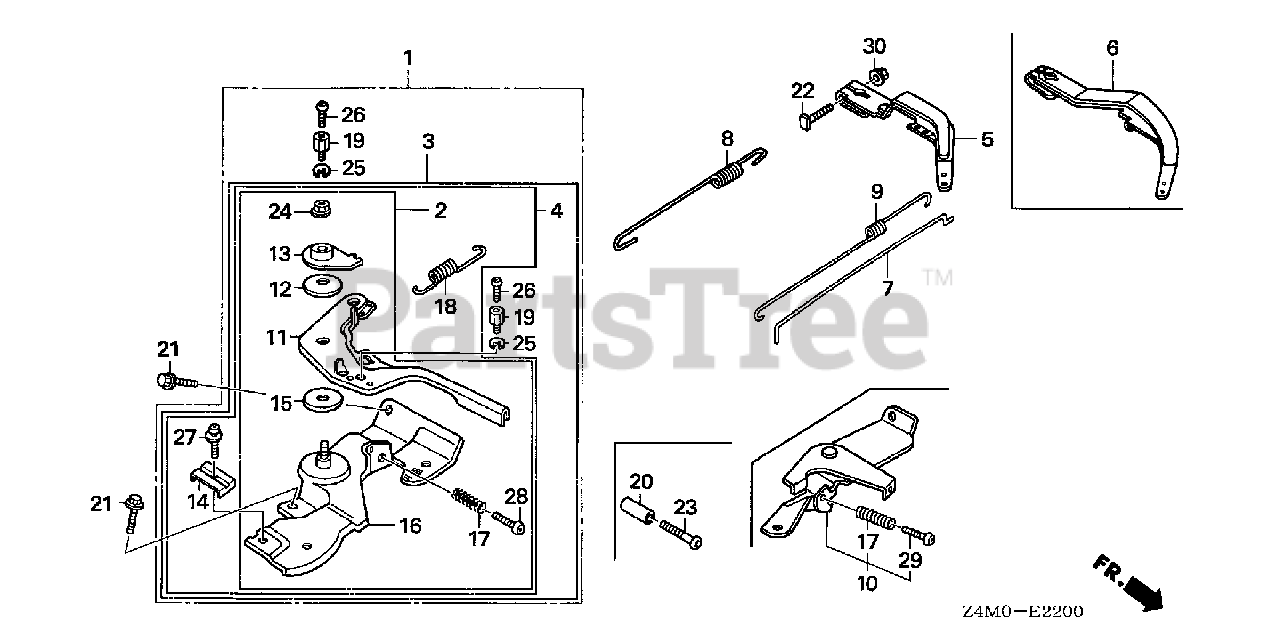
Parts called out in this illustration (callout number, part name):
3	CONTROL ASSY. (REMOTE)
5	ARM, GOVERNOR
7	ROD, GOVERNOR
8	SPRING, GOVERNOR
9	SPRING, THROTTLE RETURN
11	LEVER, CONTROL
12	SPRING, LEVER
13	WASHER, CONTROL LEVER
14	HOLDER, CABLE
15	SPACER, CONTROL LEVER
16	BASE, CONTROL (REMOTE)
17	SPRING, CONTROL ADJUSTING
18	SPRING, CABLE RETURN
19	HOLDER, WIRE
20	COLLAR, STOPPER
21	BOLT, FLANGE (6X12) (CT200)
22	BOLT, GOVERNOR ARM
23	SCREW, RECESSED (5X25)
24	NUT, SELF-LOCK (6MM)
25	CIRCLIP (5MM)
26	SCREW, PAN (4X6)
27	SCREW, PAN (5X16)
28	SCREW, PAN (5X25)
30	NUT, FLANGE (6MM)
